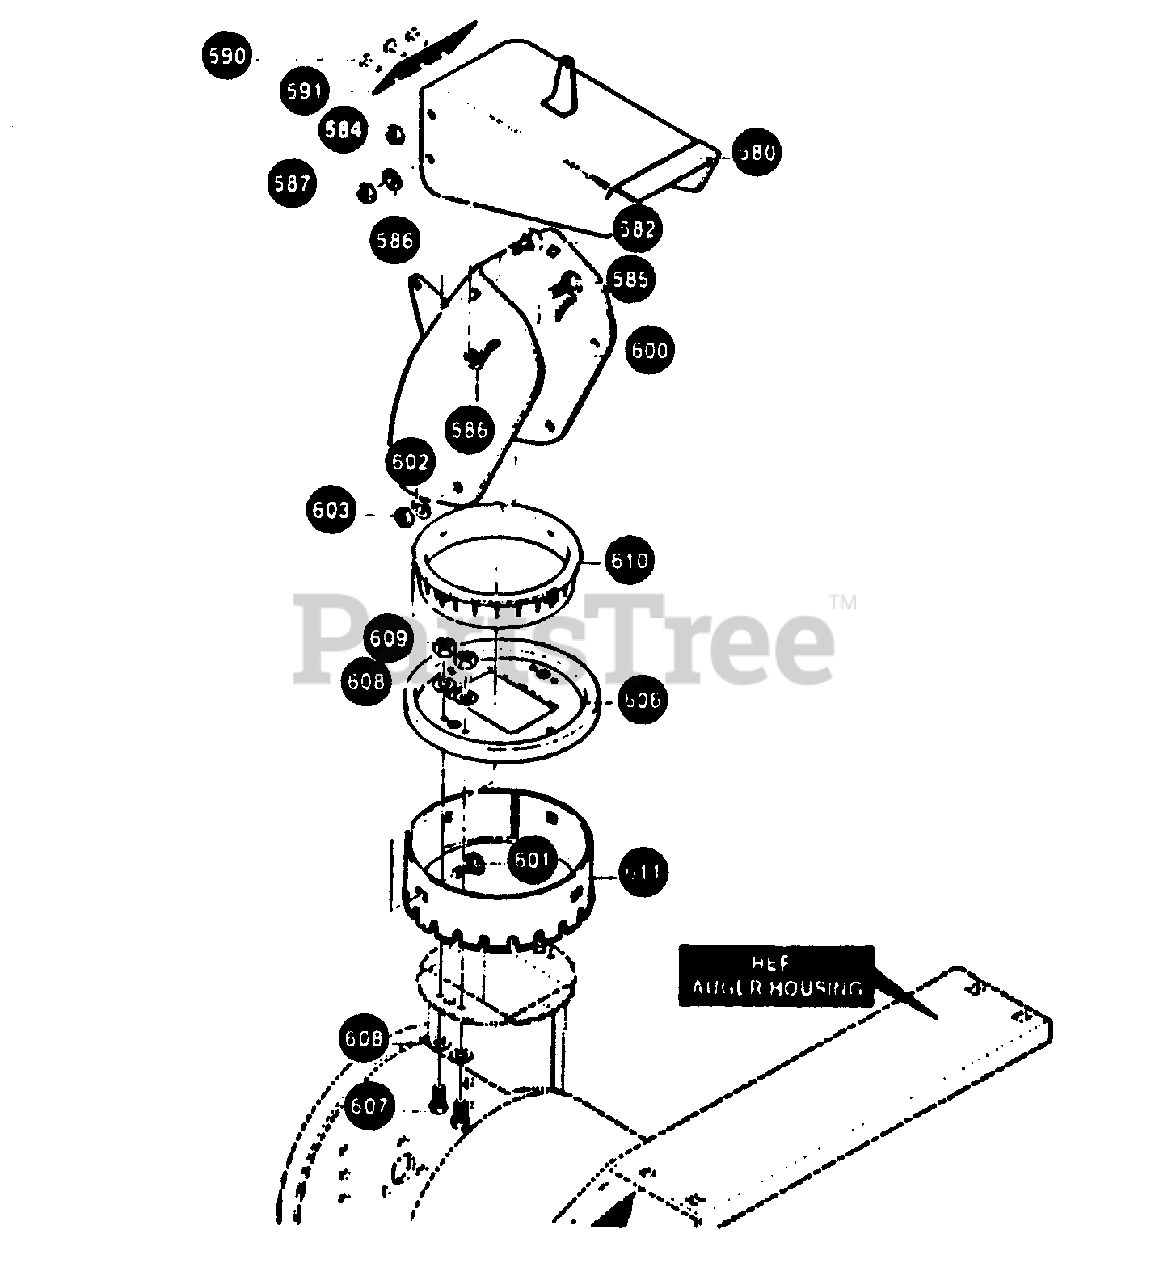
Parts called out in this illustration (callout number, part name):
580	CHUTE, UPPER
582	SCREW, 5/16-18X .75
584	NUT, 5/16-18
585	SCREW, 5/16-18X .75
586	WASHER, PLASTIC
587	NUT, 5/16-18
590	RIVET, POP
600	CHUTE, LOWER
601	BOLT, 5/16-18X1.00
602	FLATWASHER .344X .69X.065
603	NUT, 5/16-18
606	COLLAR, CHUTE
607	SCREW, 1/4-20X .75
608	FLATWASHER .281 X .63X.085
609	NUT, 1/4-20 RGHXCTRLK
610	RETAINER, RING INNER
611	RETAINER, RING OUTER
